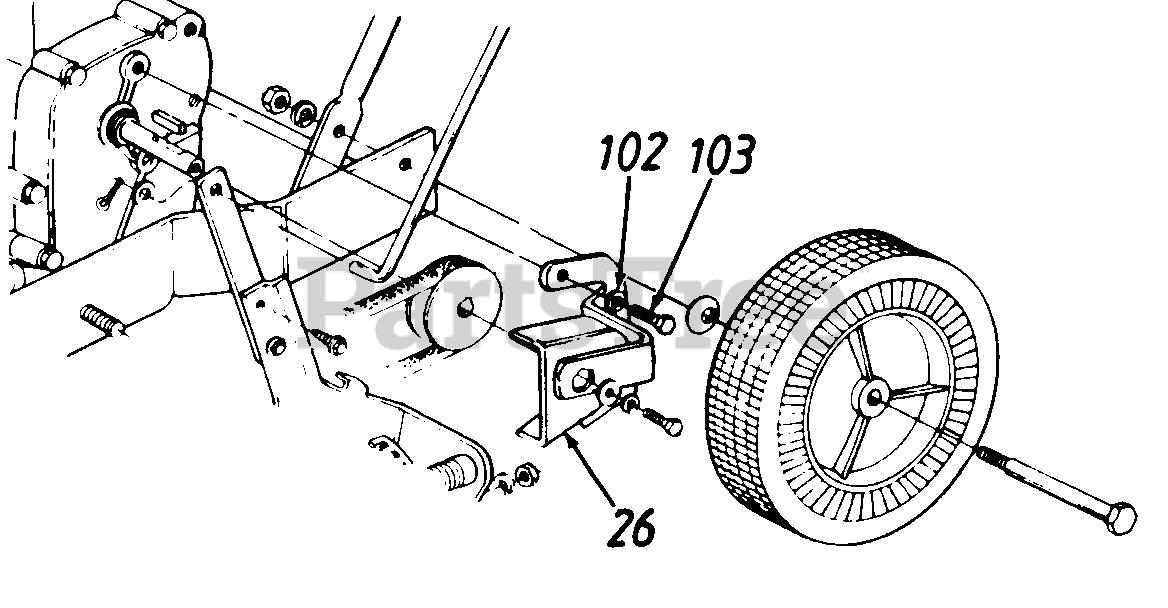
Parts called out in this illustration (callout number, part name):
26	Belt Guard Ass'y
102	L-Wash. 5/16 I.D.
103	Hex Screw 5/16-24 x .5"
